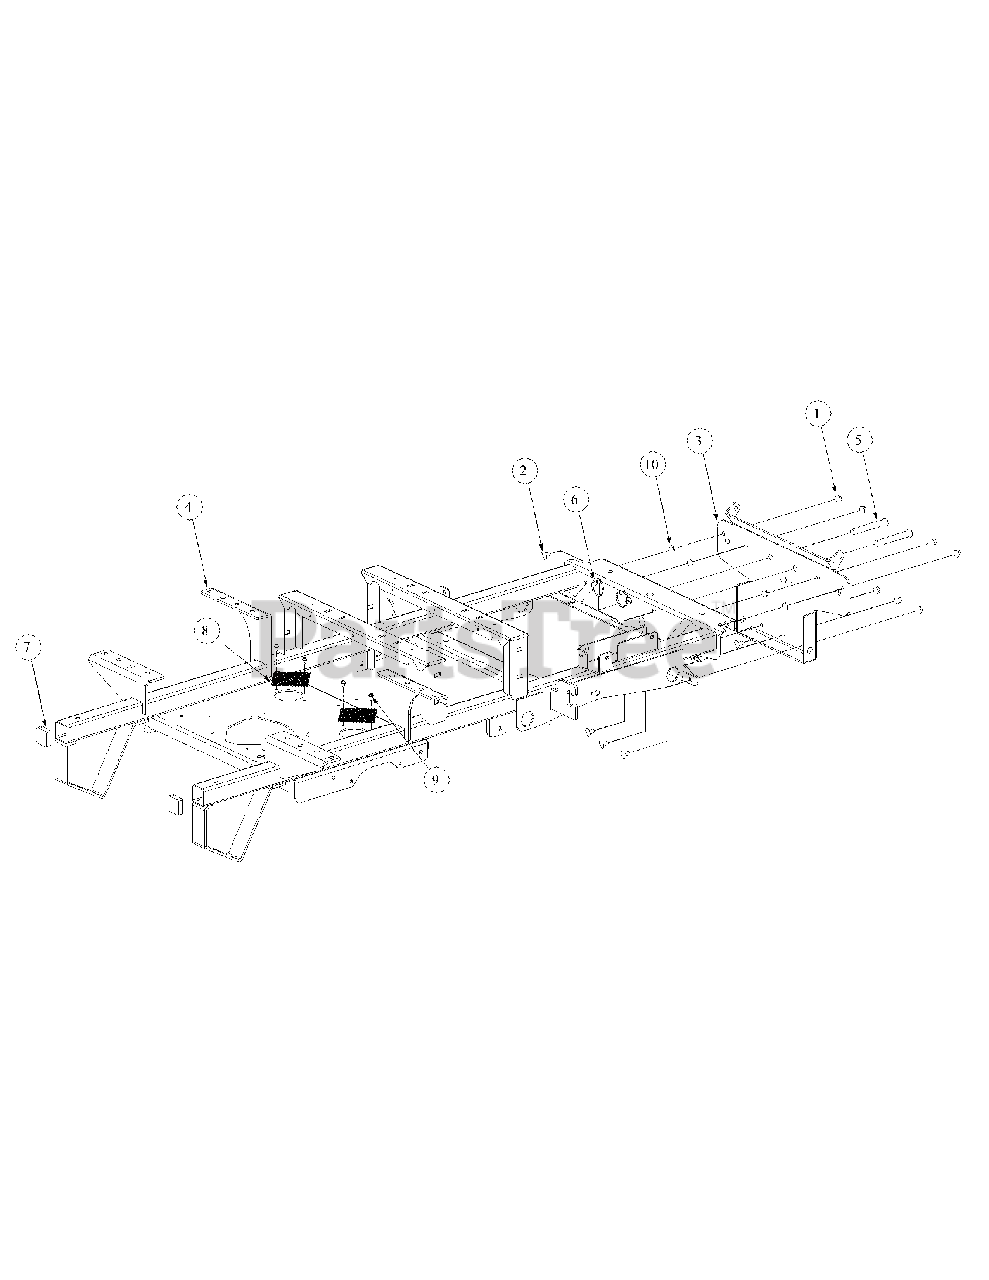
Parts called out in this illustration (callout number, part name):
1	Hex Nut, 3/8-16 Flange Lock
2	Carriage Bolt, 3/8-16 x .75 Long
3	Bracket Assembly, Frame, Front
4	Frame Assembly
5	Clevis Pin, .500 Dia x 4.375 Long
6	Linch Pin, 3/16 Dia.
7	Plug, Square Tube
8	Cover, Hydro Fan
9	Screw, TT, 1/4-20, 0.5
10	Push Retainer, 3/8
